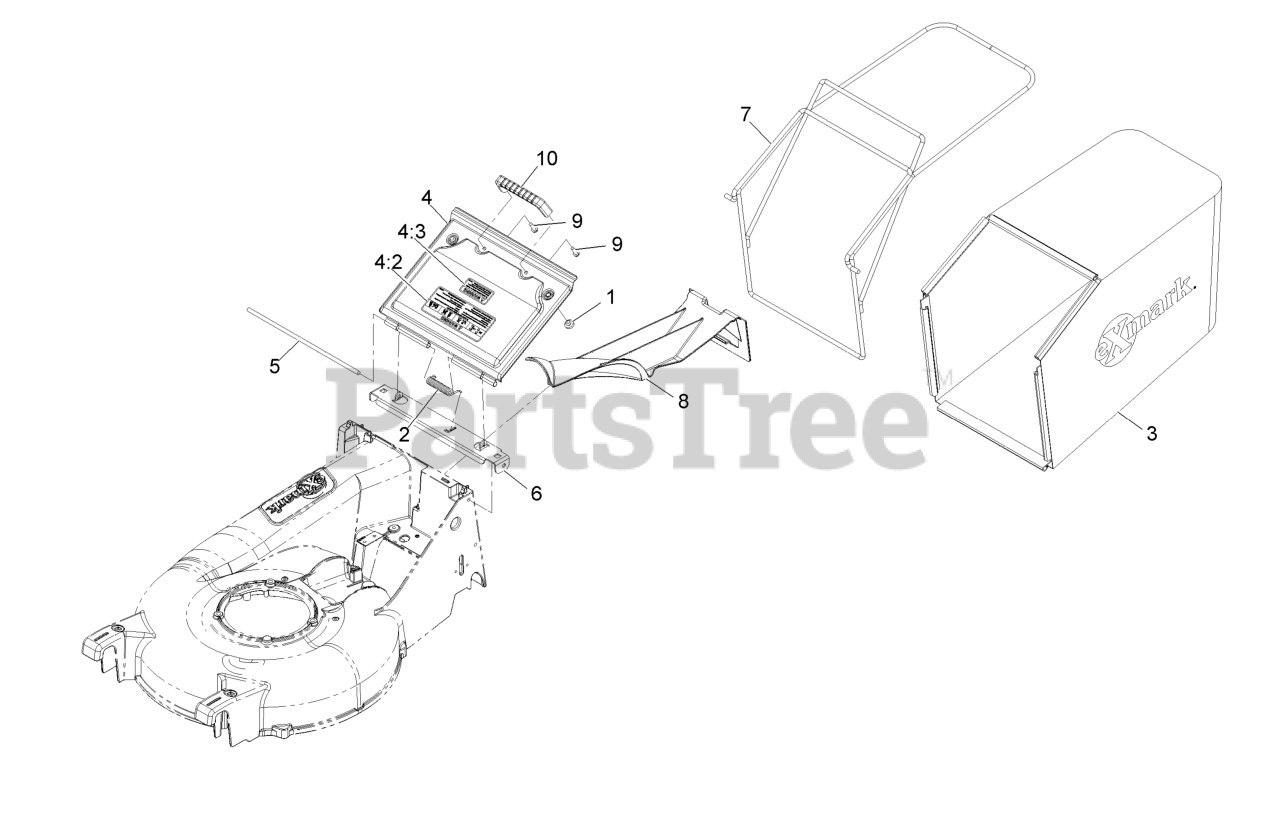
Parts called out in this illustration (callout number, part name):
2	SPRING-TORSION,COVER
3	BAG,GRASS P21
4	DOOR W/DECAL
4:2	DECAL-WARNING
4:3	DECAL-WARNING DOOR SM
5	ROD,DOOR PIVOT
6	BRACKET-DOOR P21
7	WLD,BAG FRAME
8	PLUG,MULCH
9	SCREW-HWH
10	HANDLE-DOOR
